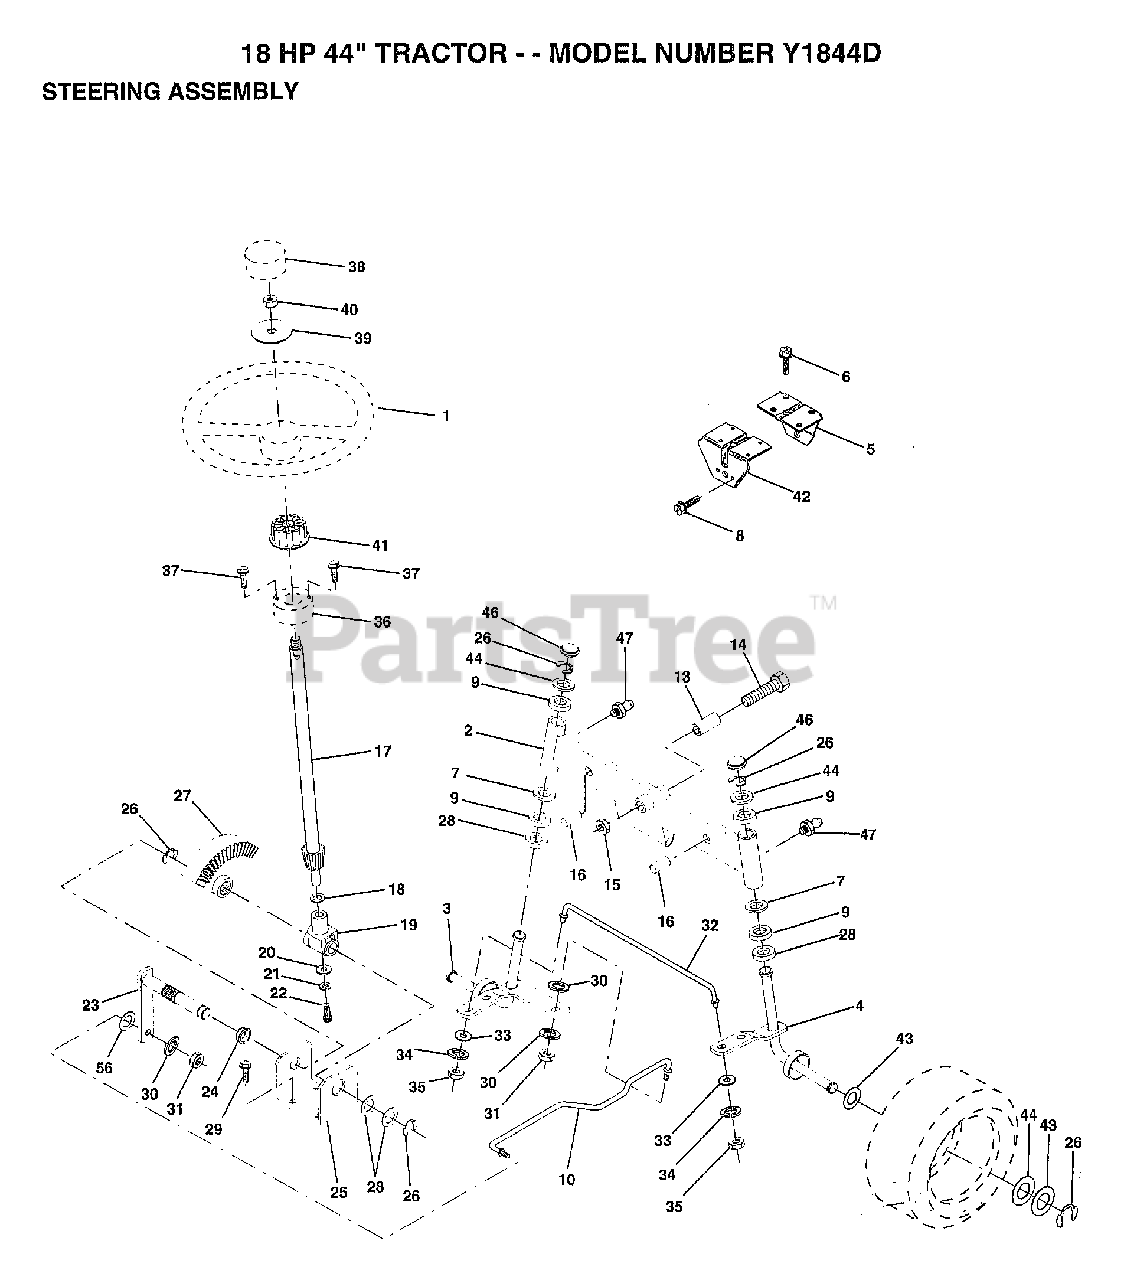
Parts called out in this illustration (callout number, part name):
1	WHEEL STR AYP BLK
2	AXLE ASM FRONT
5	SUPPORT.SADDLE.FT
6	SCREW
7	WASHER
8	SCREW LT
9	COL. SRTG. BEAR.
13	BEARING
14	BOLT LT
15	"NUT-LOC,FLANGE LT"
16	AXLE PIN
18	THRUST WASHER
19	SUPPORT.SHAFT
21	LOCKWASHER
22	"SCREW,SPECIAL"
24	NYLINER T
25	"BRKT,STEERING"
26	RING
27	GEAR SECTOR
28	WASHER .T
29	SCREW
30	LOCKWASHER
32	TIE ROD
33	WASHER M
34	LOCKWASHER
35	NUT.LOCK.5/16-24
38	CAP STEER AYP
39	WASHER
41	ADAPTER LT
42	SUPPORT-SADDL T
43	WASHER
44	WASHER
46	CAP
47	ZERK M
56	WASHER
